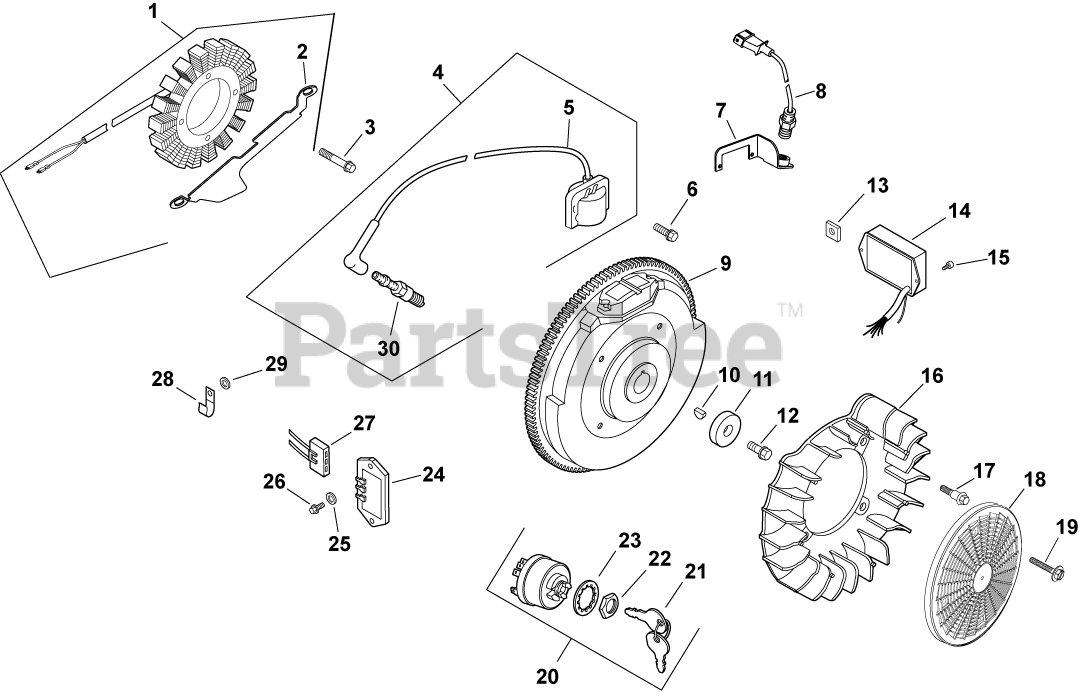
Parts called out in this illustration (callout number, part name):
1	STATOR KIT - USE 237878-S
2	BRACKET, STATOR WIRE
3	SCREW, M5X0.8X25 - (#25086402S)
4	IGNITION MODULE KIT-USE 25 707 01-S
5	MODULE, IGNITION USE 24 707 05-S
6	SCREW, FLG THD FRM M5X.8X20-(#25086399S)
7	BRACKET, SPEED SENSOR-USE 24 126 171-S
8	SENSOR, SPEED-USE 24 418 14-S
9	FLYWHEEL ASSEMBLY-USE 24 025 58-S
10	KEY, 3/16" X 5/8"
11	WASHER, FLAT 13/32"
12	SCREW, FLG M10X1.5X45 - (#25086361S)
13	NUT, PLASTIC
14	MODULE, SPEED ADVANCE -USE 24 755 172-S
15	SCREW, PHL HD #11-16X1/2"
16	FAN (WITH HOLE)-USE 24 157 16-S
17	BOLT, SHOULDER
18	SCREEN, GRASS-USE 24 162 45-S
19	SCREW, FLG SEMS M4X.7X25
20	SWITCH ASSY, KEY (KM)-USE 25 099 32-S
21	KEY, SET OF 2
22	NUT, KEY SWITCH
23	WASHER, INTERNAL TOOTH
24	REG/RECT-15 AMP (KM)-USE 41 403 10-S
25	WASHER, FLAT 1/4" (O.D. 1/2")
26	SCREW, PHL HD #11-16X7/8"
27	CONNECTOR, BODY (KM)-USE 25 155 41-S
28	CLIP, CABLE
29	WASHER, FLAT 3/16"
30	SPARK PLUG - DISCONTINUED
30	SPARK PLUG, RFI
